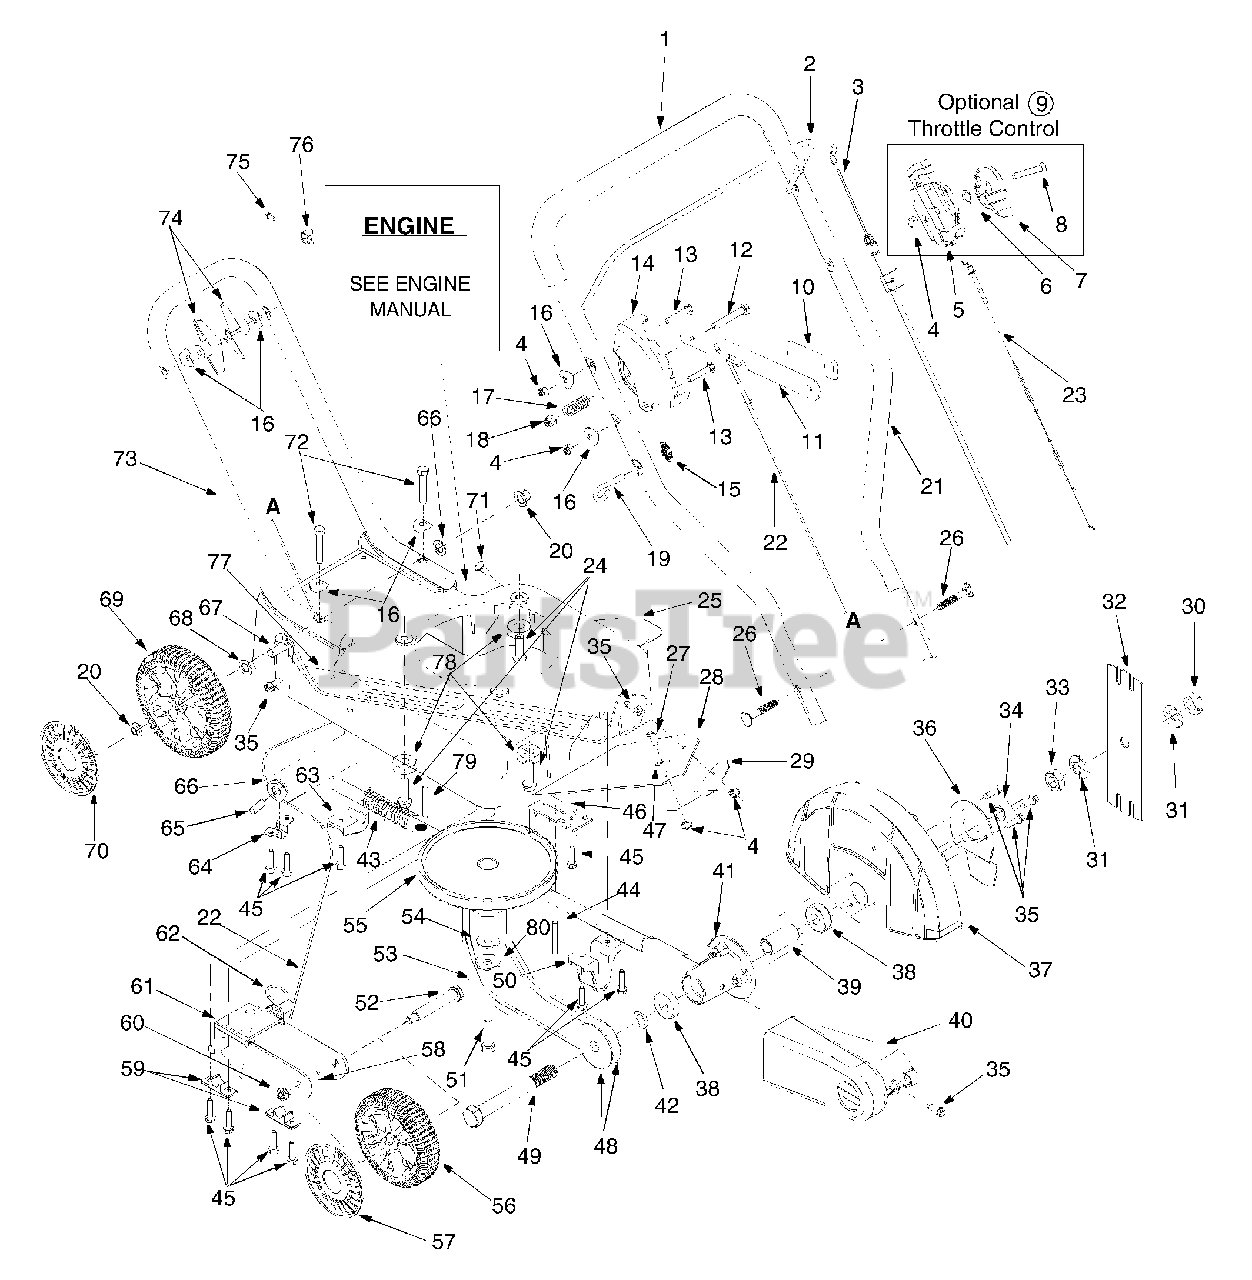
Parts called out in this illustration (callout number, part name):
1	Foam Grip
3	Control Cable 44" B&S
4	Hex Lock Nut 1/4-20 Thd.
5	Throttle Hsg.
6	Cur. Wash. .663" I.D. x .980" O.D.
7	Throttle Lever
8	Screw Oval C-Sunk 1/4-20 x 1.81" Lg.
9	Throttle Comp.
10	Depth Lever Grip
12	Hex Screw 5/16-18 x 2.0" Lg.
13	Carriage Bolt 1/4-20 x 1.25" Lg.
14	Depth Bracket
15	Handle Knob
16	Washer .320 I.D. x .93 O.D.
17	Compression Spring .550" O.D. x 1.3" Lg.
18	Hex Lock Nut 5/16-18 Thd.
19	Eye Bolt 1/4-20 Thd.
20	Push Cap
23	Throttle Cable
24	Tapp Screw w/Hex LWsh 3/8-16 Thd.
25	Edger Base Ass'y
26	Carriage Bolt 5/16-18 x 2.0" Lg.
27	Hex Screw 1/4-20 x .50" Lg.
28	Discharge Shield Deflector
29	Deflector Keeper
30	Hex Jam Nut 5/8-18 Thd.
31	Bell Wash. .63" I.D. x 1.25" O.D. x .18"
33	Hex Jam Nut 5/8-18 Thd.
34	Spacer .628" I.D. x .875" O.D. x .545" Lg.
35	Hex Scr. w/Wash.: TT: 1/4-20 x .75" Lg.
38	Bearing Ass'y .62" I.D. x 1.38" O.D. x .4"
39	Spacer .628" I.D. x .875" O.D. x 1.818 Lg.
40	Belt Guard
41	Spindle w/Insert
42	Flat Washer .635" I.D. x .93" O.D. x .06
43	Compression Spring: Arbor
44	Pin 1/4-2.0" Lg.
45	Hex Screw w/Wash 1/4
46	Spindle Bracket
47	Flat Washer .283" I.D. x .75" O.D. x .030"
48	Pulley
49	Hex Bolt 5/8-18 x 5.25" Lg.
50	Front Rod Handler
51	Hex Screw: 3/8-24 x 1.25" Lg.
52	Shoulder Screw 3/8-16:.50 x 2.62" Lg.
53	V-Belt
54	Bell Wash. .396" I.D. x 1.14" O.D. x .095"
55	Engine Pulley
56	Wheel 7 x 1.5" Diamond White
57	Hubcap: Spoke w/Hole Yellow
58	Spacer .520" I.D. x .860" Lg.
59	Black Bushing .515 Dia x .62
60	Jam Lock Nut 3/8-16 Thd.
61	Front Wheel Brkt Ass'y.
62	Torsion Spring
63	Rear Rod Handler
66	Cable Roller Pulley
68	Flat Wash. .531" I.D. x .875" O.D. x .06"
69	Wheel 8 x 1.75" Diamond White
70	Hubcap: Radial Spoke Yellow
71	Carriage Screw 1/4-20 x .62
72	Hex Screw 5/16-18 x 1.75" Lg.
75	Hex Screw w/Wash.:T: #10-32 x .625"
76	Clamp B&S Throttle
79	Roll Pin
80	Flat Washer .38 I.D. x 1.38 O.D. x .125
